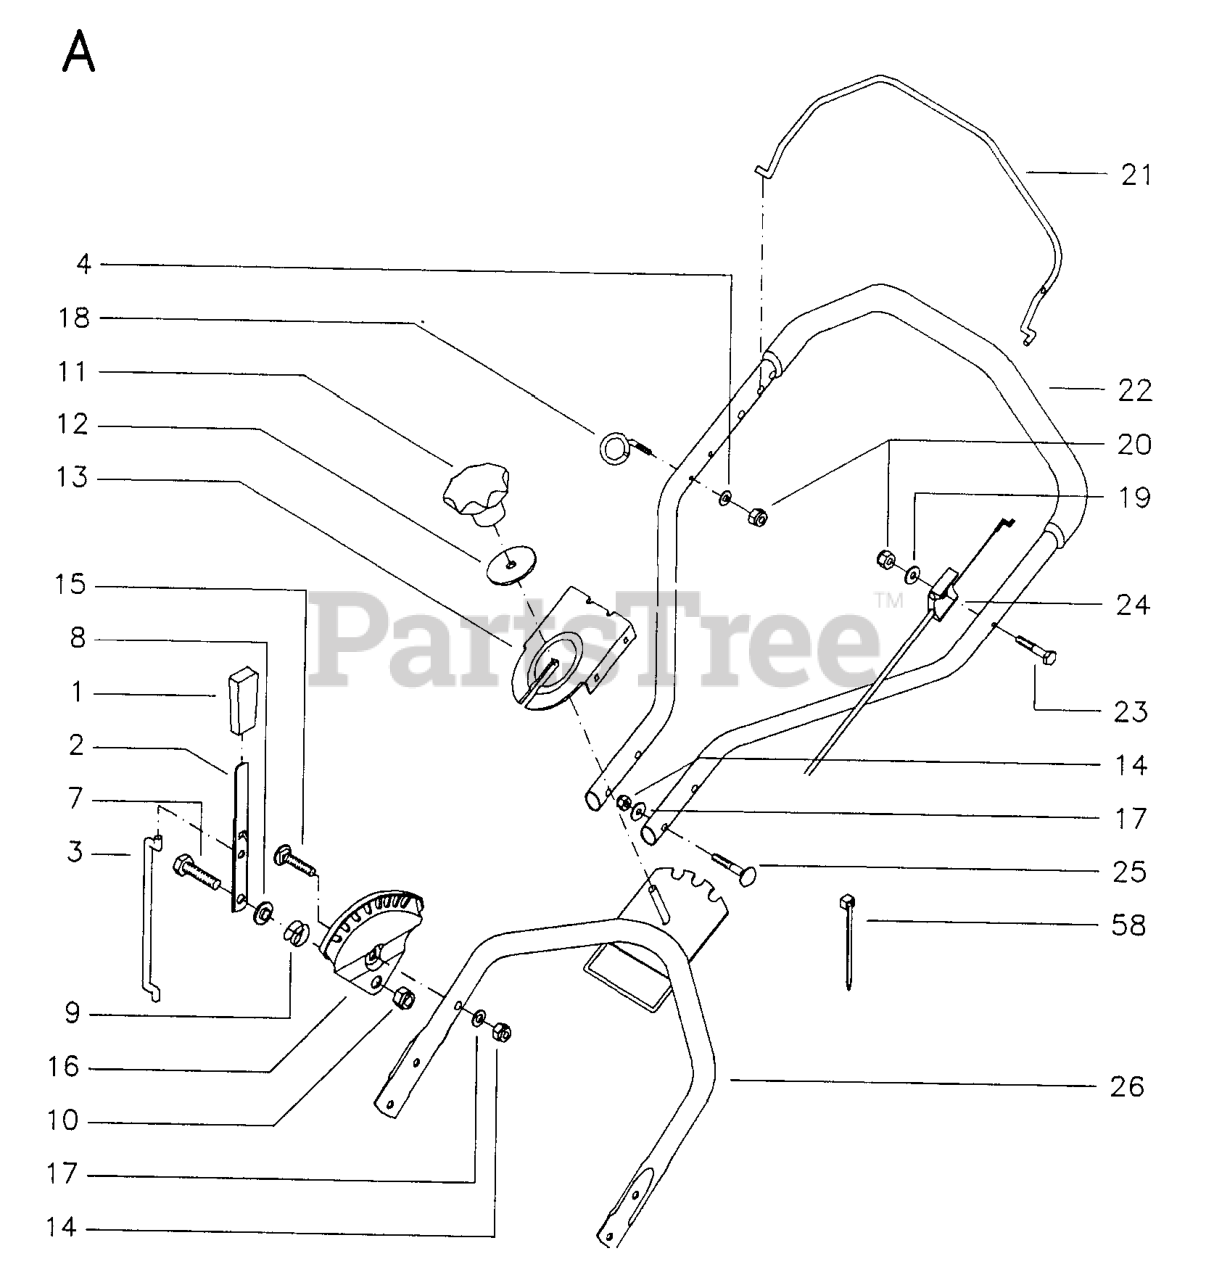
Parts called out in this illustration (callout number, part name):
2	CLUTCH ARM
9	PRESSURE SPRING
14	LOCKNUT M8
17	WASHER - 15X7.3X1.6
18	CABLE GUIDE
20	LOCKNUT M6
23	BOLT FLANGE
